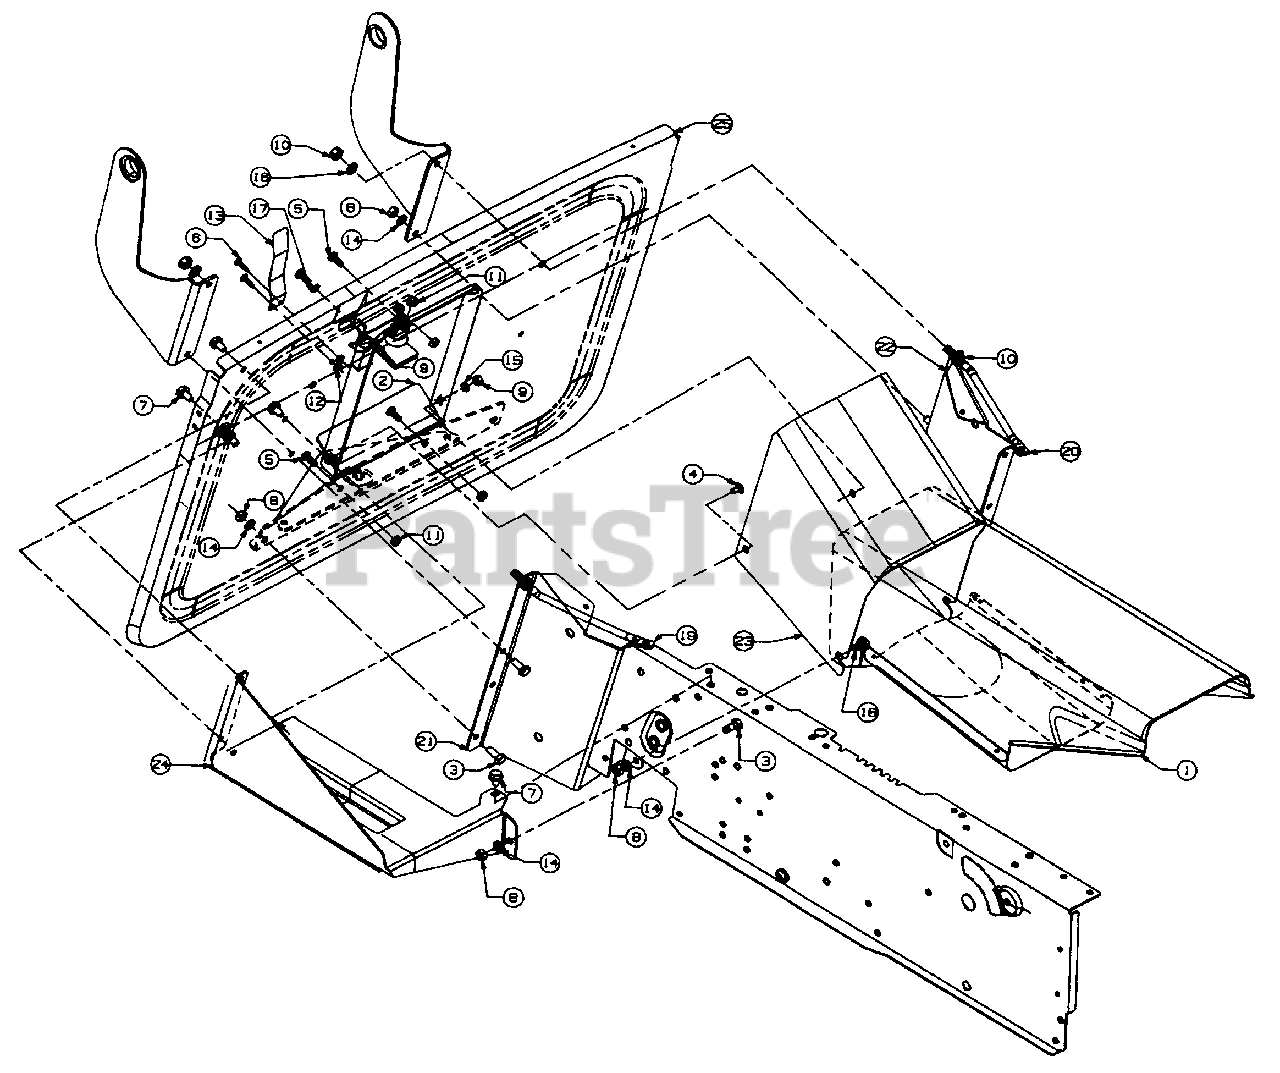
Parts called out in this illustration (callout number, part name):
1	Chute Ass'y. Center Section
2	Hitch Extension Brkt.
3	Hex bolt 5/16-18 x .75" Lg.
4	Carr. Bolt 1/4-20 x .5" Lg.
5	Hex Bolt 1/4-20 x 5/8" Lg.
6	Phillip Hd. Tap Scr. #10-24 x .75" Lg.
7	Hex Wash. Hd. SF-Tap Scr. 5/16 x .5" Lg.
8	Hex Nut 5/16-18 Thd.
9	Hex Nut 1/4-20 Thd.
10	Hex Nut 3/8-16 Thd.
11	Hex Sems Nut 1/4-20 Thd.
12	Hex Sems Nut #10-24 Thd.
13	Spring Switch
14	L-Wash. 5/16" I.D.
15	L-Wash. 1/4" I.D.
16	L-Wash. 3/8" I.D.
17	Ext. L-Wash. 1/4" I.D.
18	Shld. Bolt .437" x 1.62" Lg.
19	Brace Rod - R.H.
20	Brace Rod - L.H.
21	Hitch Plate Ext. - R.H.
22	Hitch Plate Ext. - L.H.
23	Chute Cover Brkt.
24	Battery Tray
25	Grass Catcher Support
